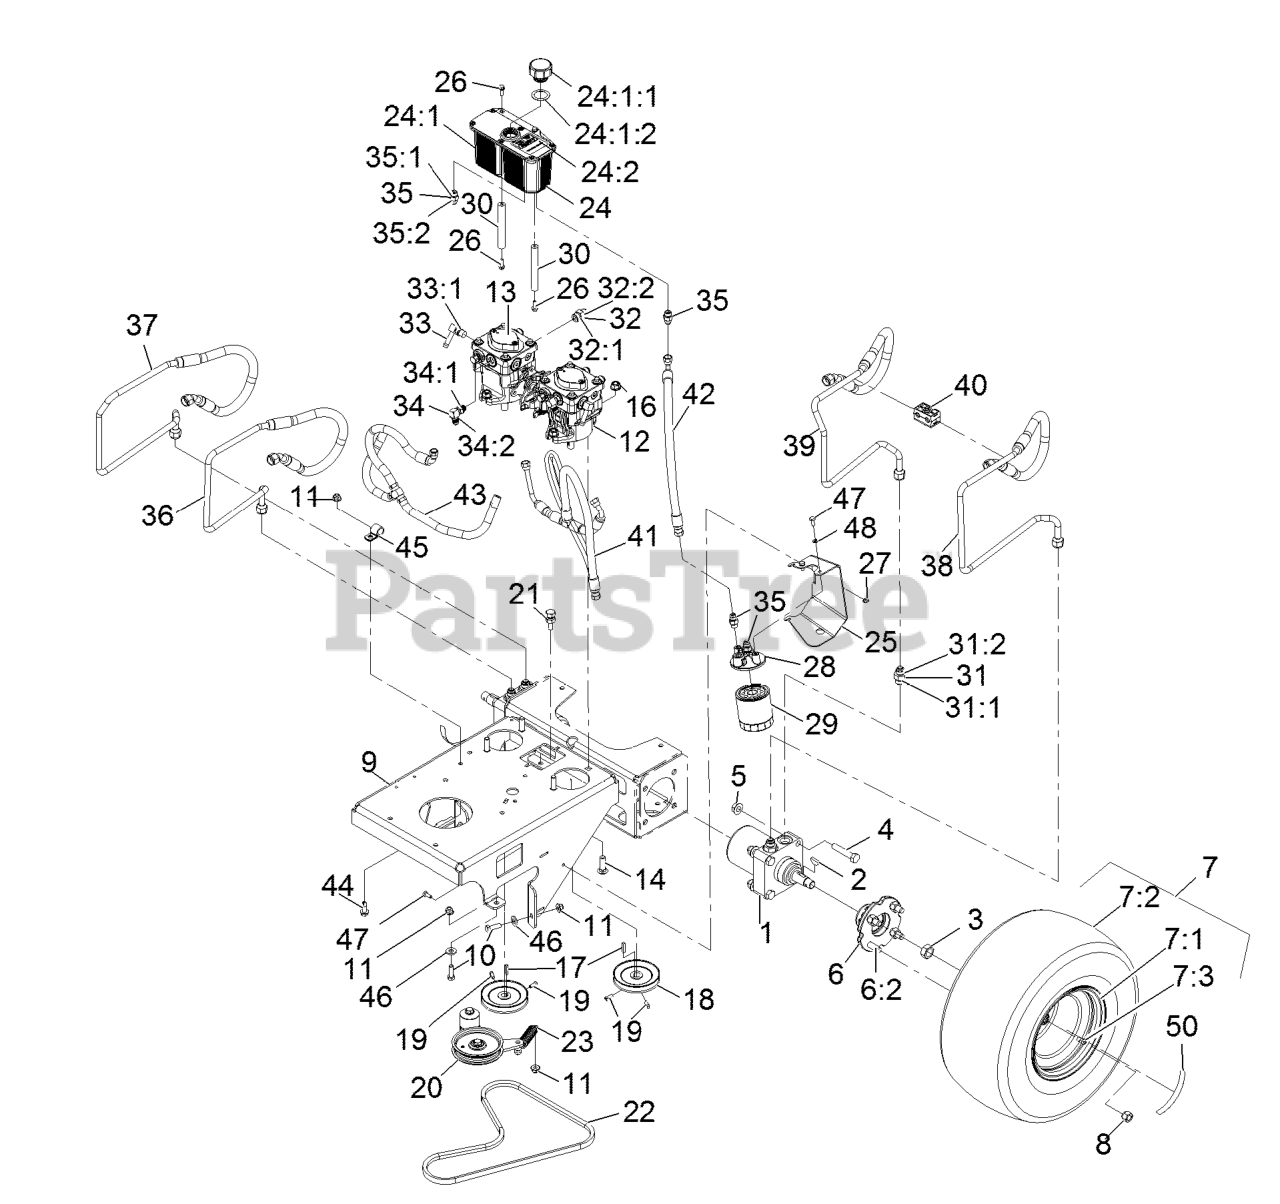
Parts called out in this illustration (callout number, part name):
1	HYD MOTOR ASM
2	KEY-WOODRUFF
3	NUT-MOTOR, WHEEL
4	SCREW-HH
6	WHEEL HUB ASM
6:2	STUD-TYPE, DRIVE
7	WHEEL/TIRE ASM
7:1	RIM-8 INCH
7:3	Stem-Valve
8	NUT-LUG
9	ENGINE BASE
10	SCREW-HH
11	NUT-HF, NI
12	PUMP - HYDRAULIC
13	PUMP-HYDRAULIC
14	SCREW-HH
16	NUT-HF, NI
18	PULLEY-PUMP
19	SCREW-SET
20	Pump Idler Asm
22	BELT-V
23	SPRING-EXTENSION
24	RESERVOIR ASM
24:1	Reservoir-Hyd
24:1:1	Cap-Reservoir, HYD
24:1:2	GASKET-CAP
24:2	DECAL-HYDRAULIC TANK
25	PLATE-FILTER MOUNT
26	SCREW-HHF
28	HEAD-FILTER
29	FILTER-25 MICRON, BI-DIRE
30	ROD-RESERVOIR STAND
31	FITTING-STRAIGHT
31:1	O-RING
32	FITTING-STRAIGHT
33	FITTING-ELBOW, 90
33:1	O-RING
34	FITTING-90 DEG
35	FITTING-STRAIGHT
36	HOSE-HARDLINE
37	HOSE-HARDLINE
38	HOSE-HARDLINE
39	HOSE-HARDLINE
40	CLAMP, STAUFF 212,7/12,7
41	HOSE-ASM CHARGE
42	HOSE ASM-HYD LP 3/8X14.4
43	HOSE ASM - HYD 3/8
44	SCREW-TAPPING
45	CLIP-LOOM
46	WASHER-BELLEVILLE
47	SCREW-HH
48	WASHER-LOCK
